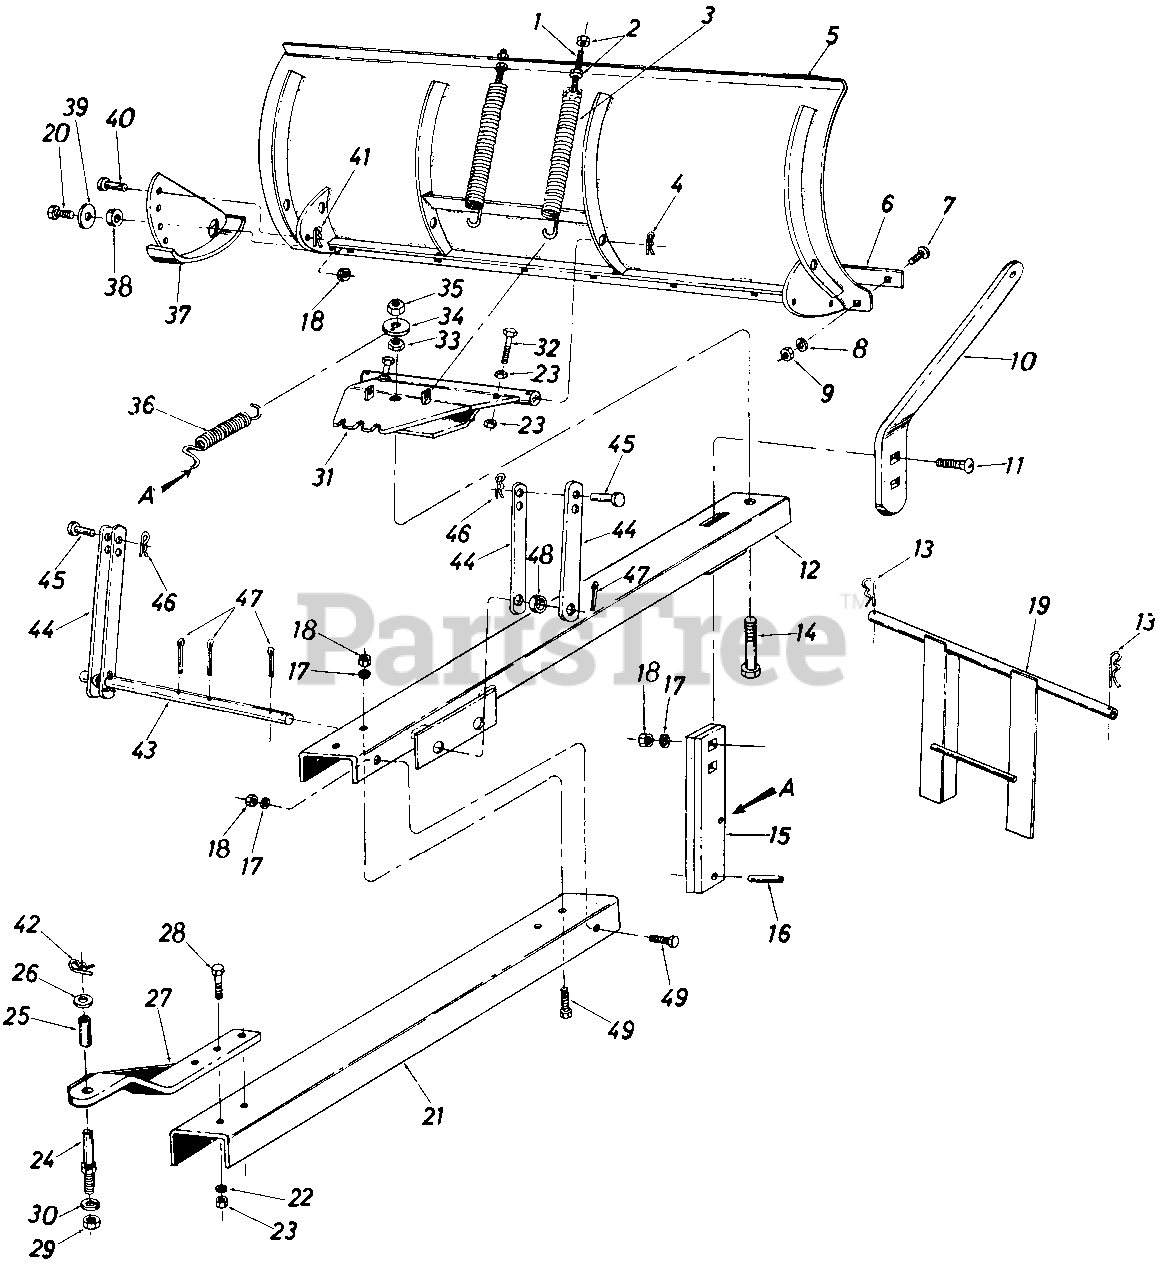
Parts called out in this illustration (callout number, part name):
1	Hex Scr. 3/8-16 x 4.50" Lg.
2	Hex Nut 3/8-16 Thd.
3	Blade Adjustment Spring
4	Hair Pin Cotter: 5/32
5	54" Blade Ass'y.
6	Wear Plate
7	Carriage Bolt 5/16-18 x .75" Lg.
8	L.-Wash. 5/1 6" Scr.
9	Hex Nut 5/16-18 Thd.
10	Lock Extension Bar
11	Carriage Bolt 3/8-16 x 1.25" Lg.
12	Front Push Bar Ass'y.
13	Hair Pin Cotter: 5/32
14	Hex Scr. 3/4-10 x 3.50" Lg.
15	Angle-Lock Bar
16	Spring Pin Spirol .25" Dia. x 1.00" Lg.
17	L.-Wash. 3/8" Scr.
18	Hex L.-Nut3/8-16 Thd.
19	Guide Bracket Ass'y.
20	Hex Scr. 3/8-16 x .75" Lg.
21	Rear Push Bar Channel
22	L.-Wash. 1/2" Scr.
23	Hex Nut 1/2-13 Thd.
24	Link Clevis Pin
25	Spacer 1 " O.D. x 21/32" I.D. x .75" Lg.
26	Fl-Wash. 21/32 I.D. x .090 O.D.
29	Hex Jam L.-Nut 5:'8-18 Thd.
30	L.-Wash. 5/8" Scr.
31	Pivot Plate Ass'y.
32	Hex Scr. 1/2-13 x 2.00" Lg.
33	Hex Jam Nut 3/4-10 Thd.
34	Fl.-Wash. 3/8"
35	Hex Lock Nut 3/4-10 Thd.
36	Angle Lock Spring
37	Skid Assembly
38	Bushing: Pivot Skid
39	Fl.-Wash. .385" I.D. x 1.00" O.D.
40	Clevis Pin 5/16" Dia. x 3/4" Lg.
41	Hair Pin Cotter 3/32"
42	Hair Pin Cotter: 5/32
43	Lift Shaft
44	Lift Link
45	Clevis Pin 1/2" Dia. x 1.00" Lg.
46	Hair Pin Cotter: 3/32"
47	Cotter Pin 1/8" Dia. x 1.50." Lg.
48	Spacer: Lift Link
49	Hex Scr. 3/8-16 x 1.00" Lg.
